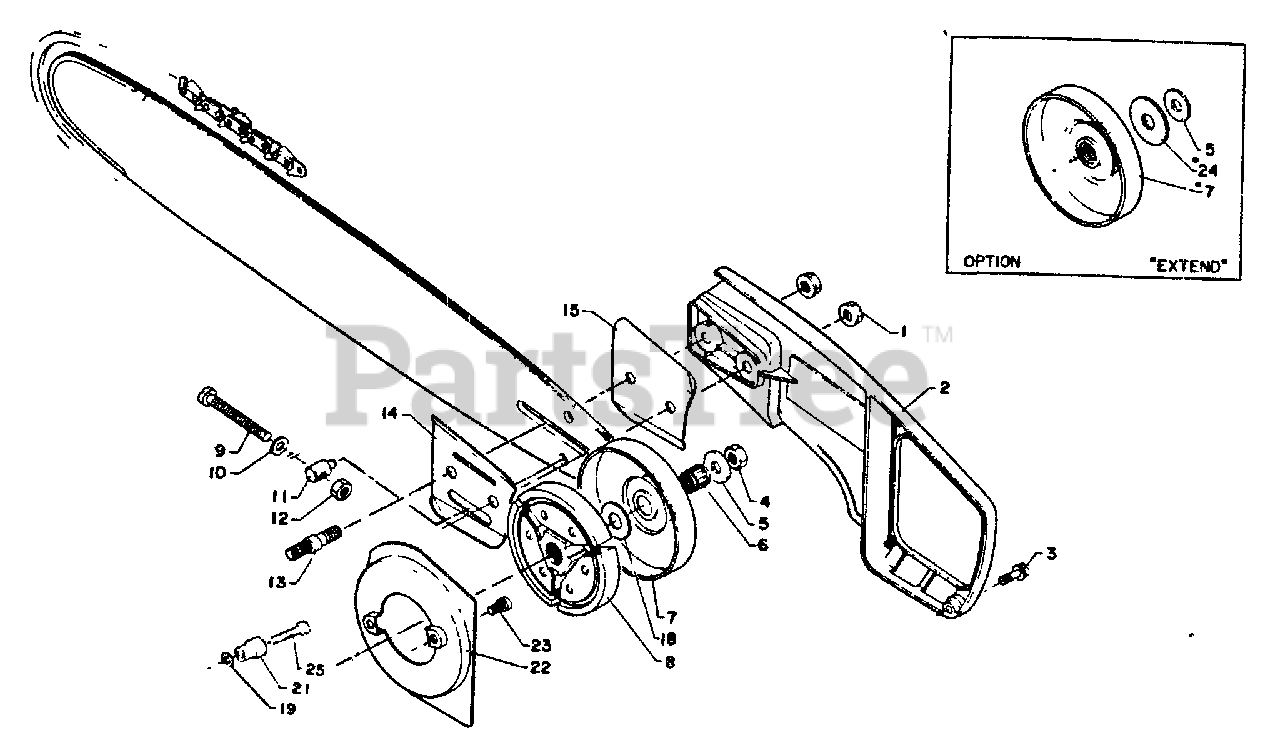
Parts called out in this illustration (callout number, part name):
1	NUT - 6 -- FLANGE
2	GUARD, SPROCKET
3	SCREW
4	LOCKNUT - 6
5	WASHER, CLUTCH
6	BEARING, NEEDLE
7	DRUM, CLUTCH
7	CASE, CLUTCH
8	CLUTCH ASSY
9	SCREW, TENSIONER
10	WASHER - 5
11	TENSIONER, CHAIN
12	LOCKNUT - 5
13	STUD, GUIDE BAR
14	PLATE, GUIDE - INNER
15	PLATE, GUIDE - OUTER
18	WASHER, CLUTCH
19	WASHER - 5
20	LOCKWASHER - 5
21	CATCHER, CHAIN
22	SEAL, DUST
23	SCREW - 4X8
24	WASHER, CLUTCH
25	SCREW - 5X25
